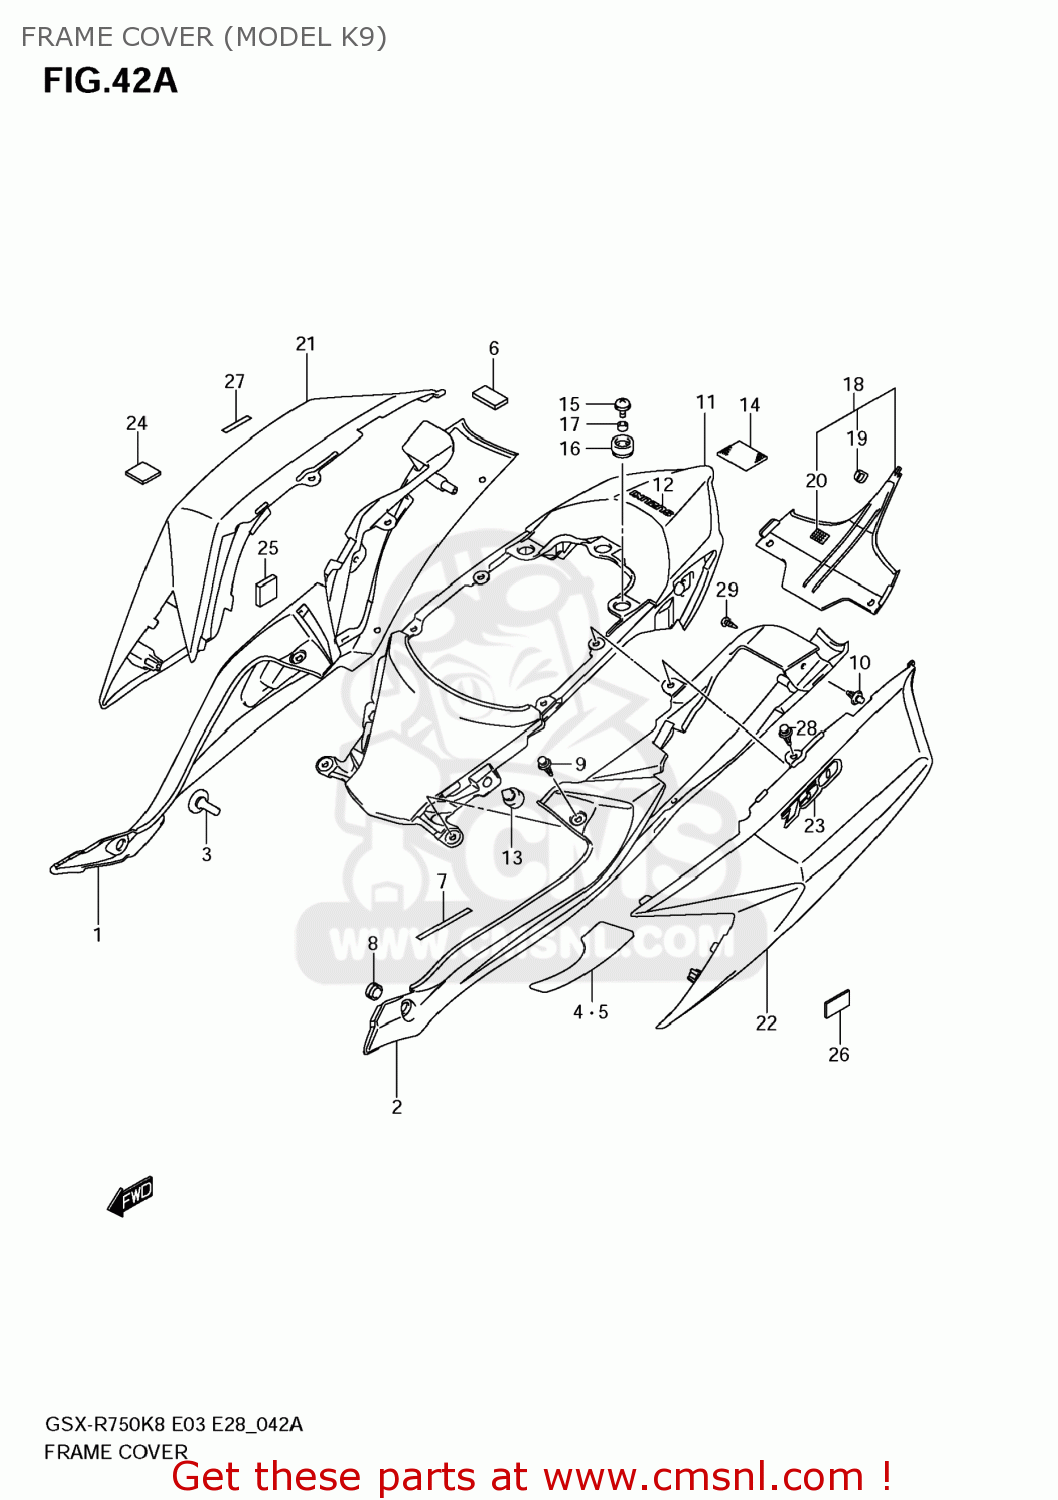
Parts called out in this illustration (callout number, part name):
1	COVER,FRAME,R(BLACK)
2	COVER,FRAME,L(BLACK)
3	CUSHION
4	TAPE,FRAME COVER,R
5	TAPE,FRAME COVER,L
6	CUSHION,FRAME COVER RR LWR
7	TAPE,FRAME COVER FR
8	CUSHION,FRAME COVER FR
9	CLIP
10	CLIP(BLACK)
11	COVER,FRAME CTR
12	EMBLEM,SUZUKI
13	CUSHION(11.5X22X20)
14	FASTENER,RR COMB LAMP
15	SCREW(6X20)
16	CUSHION,FRAME COVER RR
17	SPACER(6.5X10X7)
18	COVER,FRAME RR CTR
19	CUSHION,FRAME COVER RR CTR
20	FASTENER,FRAME COVER
21	COVER,FRAME RR,R
22	COVER,FRAME RR,L
23	EMBLEM,FRAME COVER
24	CUSHION,COVER
25	CUSHION,SIDE
26	CUSHION,SEAT TAIL COVER LWR RR
27	TAPE,SEAT TAIL COVER
28	CLIP
29	SCREW
